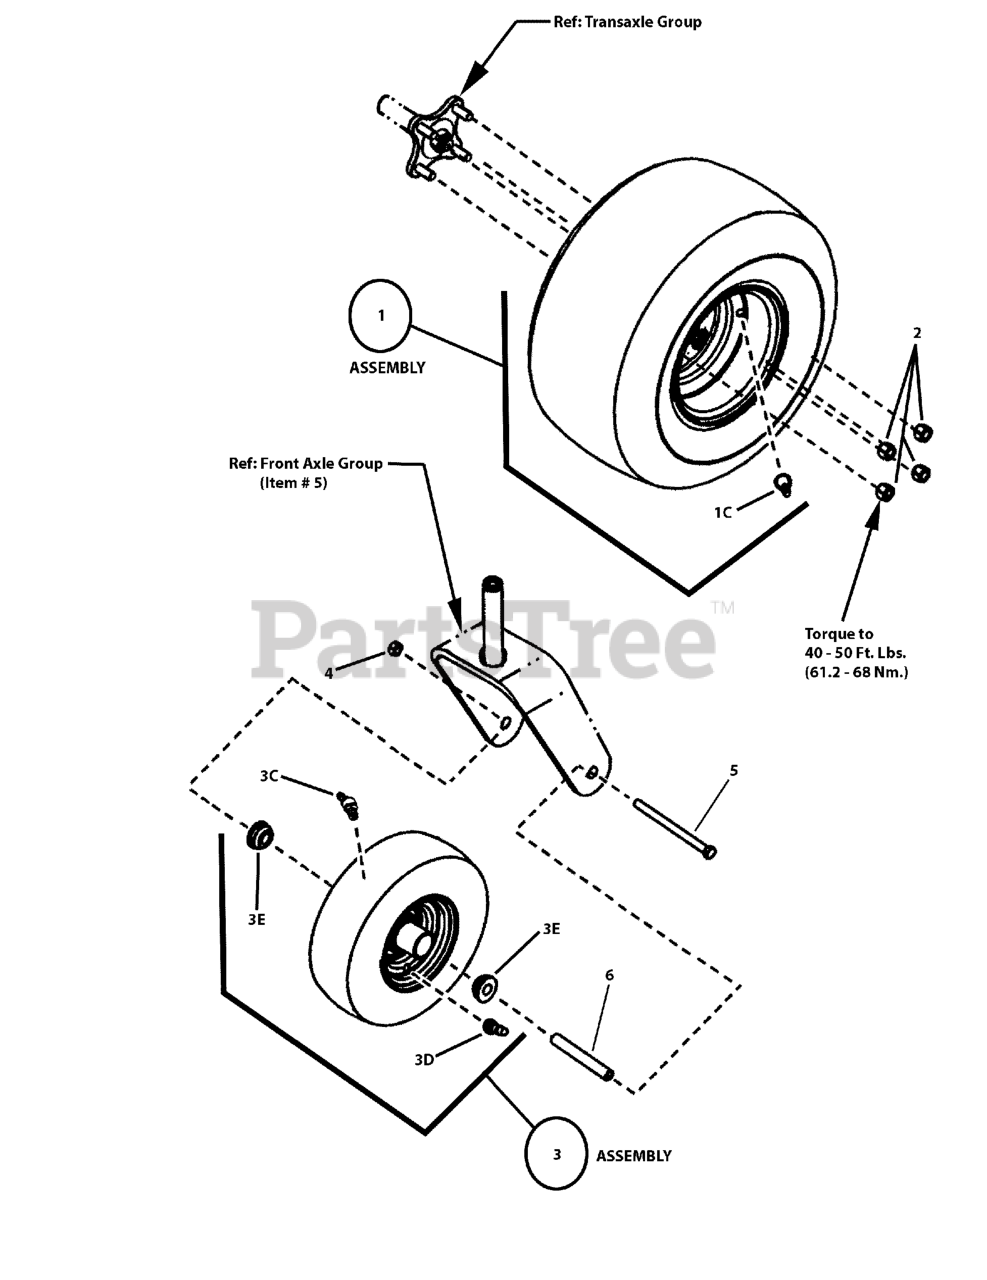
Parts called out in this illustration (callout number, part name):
1	ASSEMBLY, Tire & Wheel (Rim)
1C	AIR VALVE STEM, Snap-In
2	LUG NUT, 1/2 - 20 Tapered Seat, YZ
3	ASSEMBLY, Wheel & Tire Sears ZTS 11 x 4-5
3C	GREASE FITTING, (8M x 1 threads, 45 degree)
3D	VALVE, Air
3E	BUSHING, 0.632ID 1.377OD, .62
4	NUT, 7/16-14 Hex Center Lock, GR 5 or B
5	SCREW, 7/16-14NC x 6", Hex Head Cap, GR 5, YZ
6	TUBE, Caster Wheel
